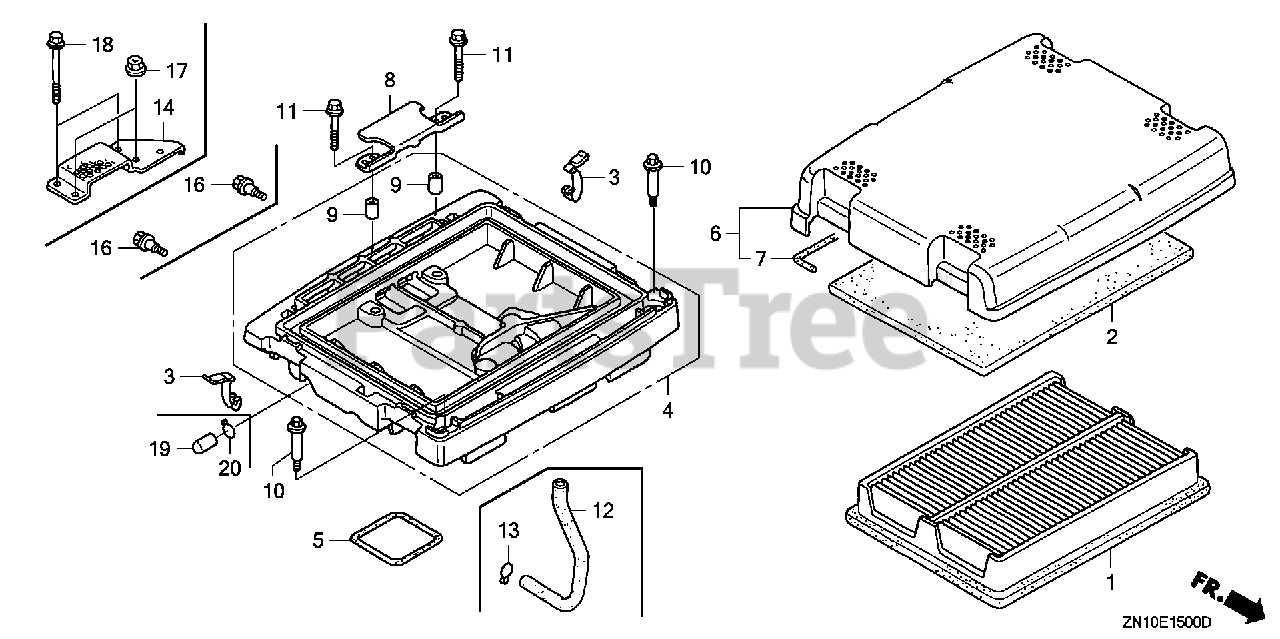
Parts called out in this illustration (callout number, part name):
1	ELEMENT, AIR CLEANER
2	FILTER (OUTER)
3	CLIP, AIR CLEANER
4	HOUSING, AIR CLEANER
5	SEAL, AIR CLEANER HOUSING
6	COVER ASSY., AIR CLEANER
7	SEAL, AIR CLEANER COVER
8	PLATE, AIR CLEANER SETTING
9	COLLAR A, AIR CLEANER
10	BOLT, SPECIAL (5MM)
11	BOLT, FLANGE (6X28)
